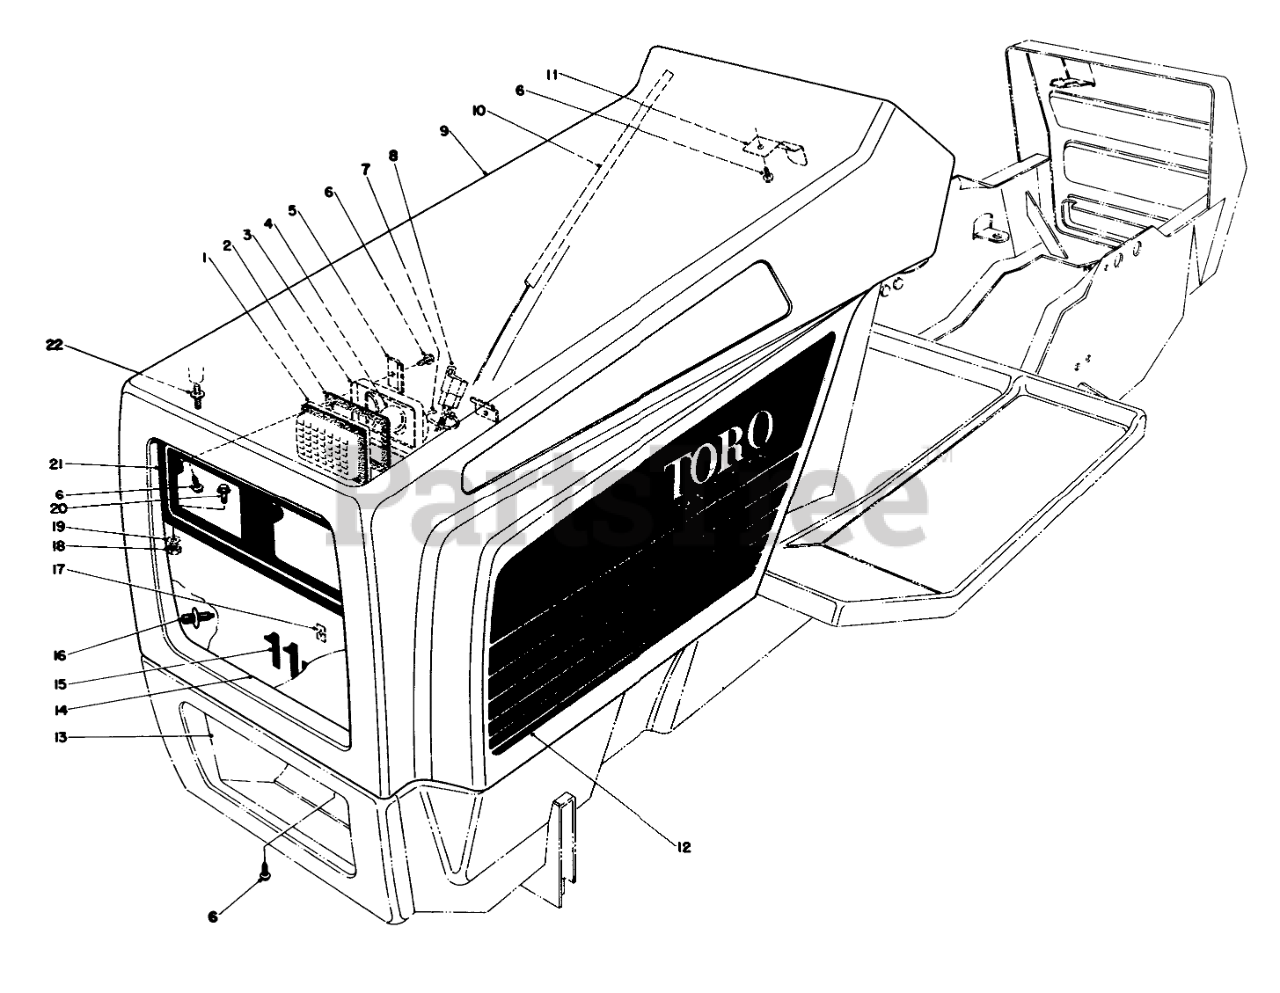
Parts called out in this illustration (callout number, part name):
1	Lens
2	Lens Gasket
3	Reflector Assembly
5	HEADLIGHT CLAMP
6	SCREW-HWHTF
7	TIE-CABLE
8	CONNECTOR BODY
9	Hood (Incl. Ref. #16 & 22)
10	RUBBER EXT SEAL
11	SPRING LATCH
12	Decal-Hood L.H.
13	LOWER GRILLE
14	HEADLIGHT GRILLE
15	Name Plate-Grille
16	HINGE BRKT STUD
18	NUT-LOCK, SIDE
19	WASHER-FLAT
20	SCREW-SHWH
21	HEADLIGHT PANEL B
22	Stud Hood Duct
